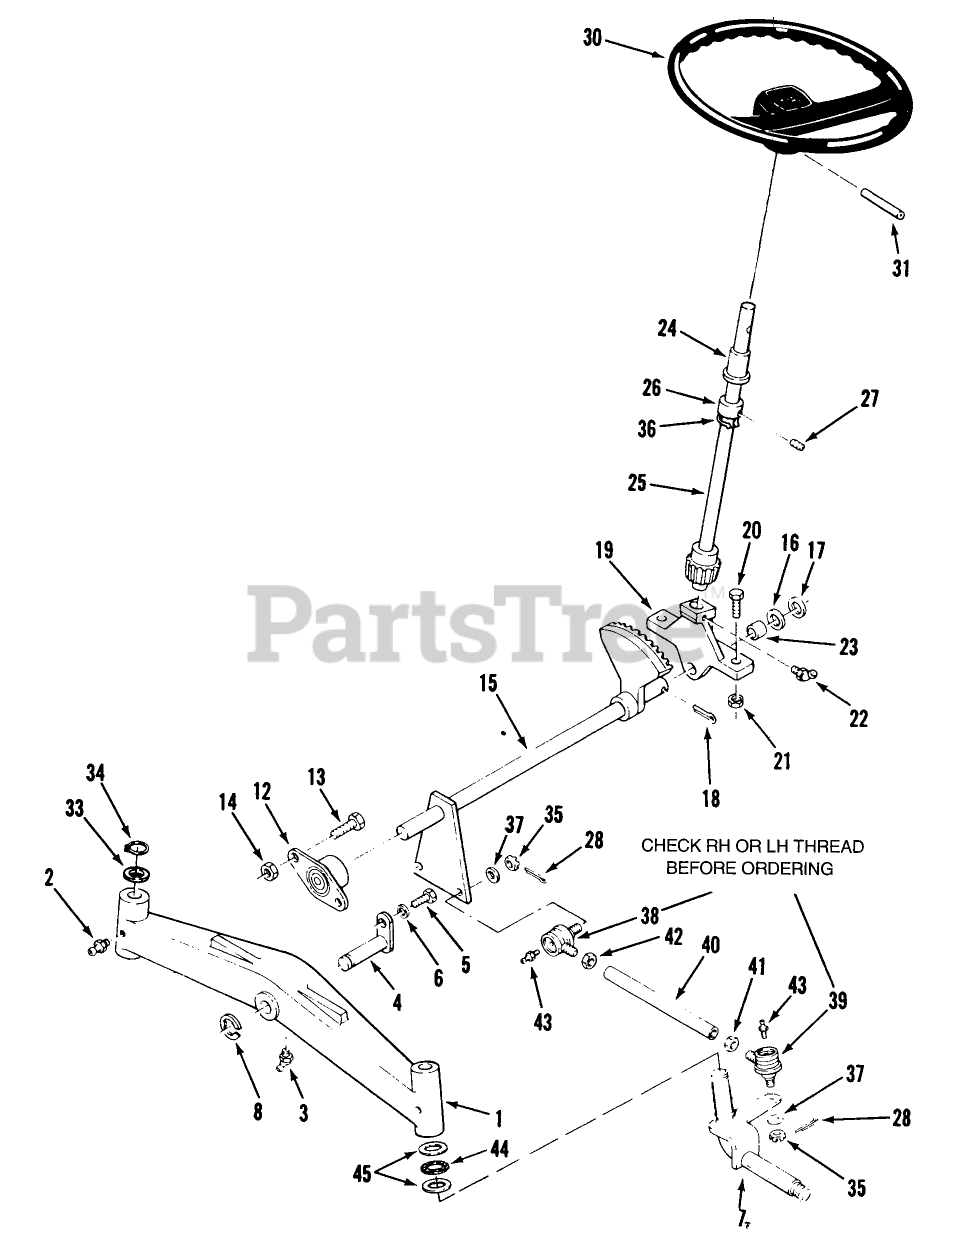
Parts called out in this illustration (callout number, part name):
3	FITTING-GREASE
4	PIN AND PLATE ASM
8	E-RING
12	BEARING-FLANGED
16	WASHER-SHIM
17	WASHER
22	FITTING-GREASE
23	BEARING-BRONZE
24	BEARING-FLANGED
26	COLLAR
33	WASHER
36	RING-RETAINING
